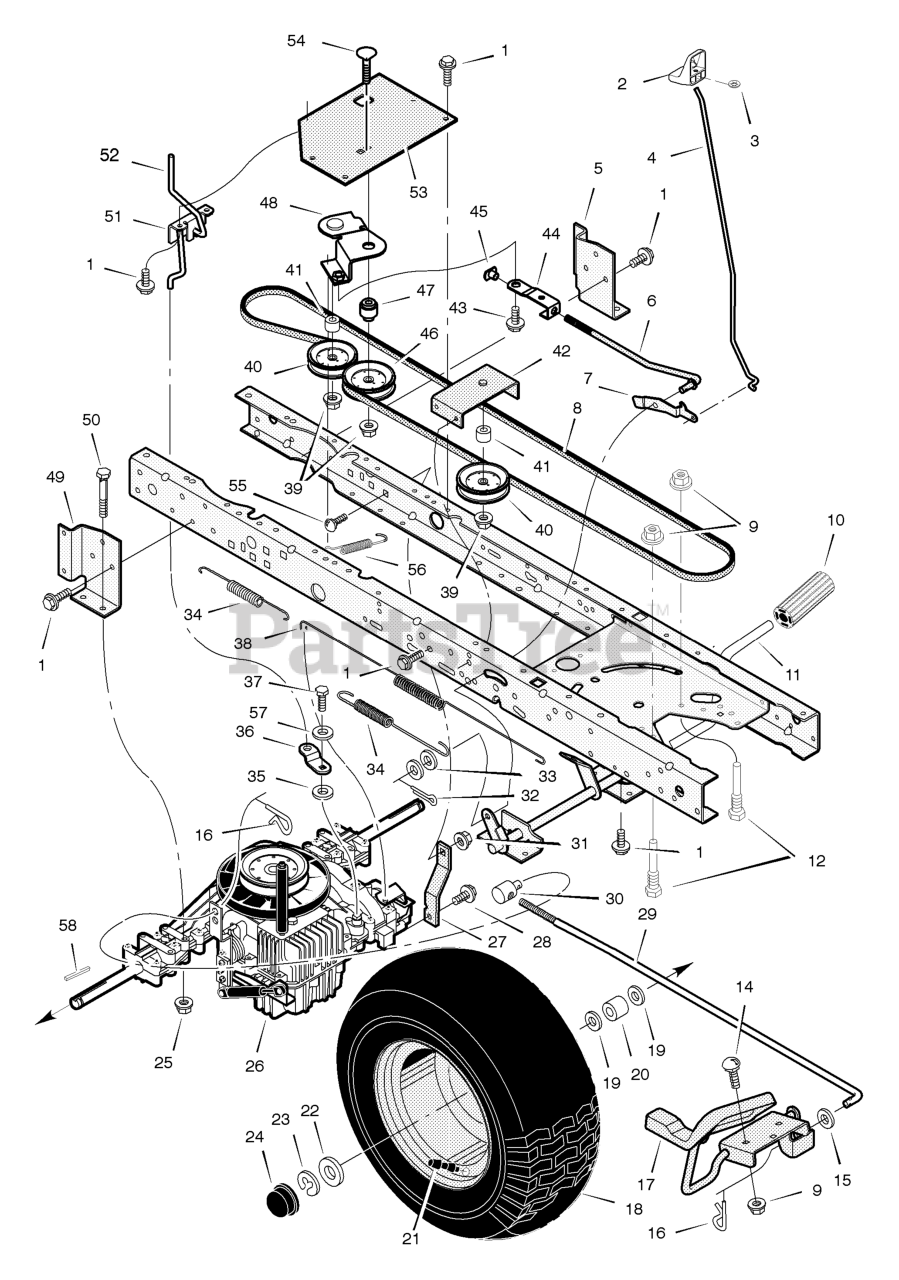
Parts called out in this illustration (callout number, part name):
2	Knob, Parking Brake
3	Retainer, Push
4	Rod, Parking Brake
5	Bracket, Left Transaxle
6	Rod, Clutch
7	Latch, Parking Brake
8	V-Belt, Drive
9	Nut, Flange
10	Pedal, Brake/Clutch
11	Assembly, Brake Pedal
12	Screw, Guide
14	Bolt, Carriage
16	Pin, Hair
17	Pedal Assembly, Hydro
18	Wheel & Tire Ass'y - 20"
20	Spacer
21	Stem, Valve
24	Cap, Hub
25	Nut, Centerlock
26	Transaxle, Peerless **
27	Strap, Torque
29	Rod, Control
30	NUT, Adjusting
31	Nut, Centerlock
32	Pin, Cotter
34	Spring, Extension
36	ARM, Disconnect
37	Capscrew
38	Spring, Brake
39	Locknut, Flange
40	Pulley, Idler
42	Bracket, Idler Assembly
43	Bolt, Shoulder
44	Link, Clutch
45	Nut, Tee
46	Pulley, Idler
47	Bushing, Pivot
48	Arm Assembly, Idler
49	Bracket, Right Transaxle
50	Bolt, Hex
51	Bracket, Disconnect
52	Rod, Disconnect
53	Bracket, Idler Pivot
54	Bolt, Carriage
55	Bolt, Carriage
56	Spring, Clutch
58	Key, Square 3/16
